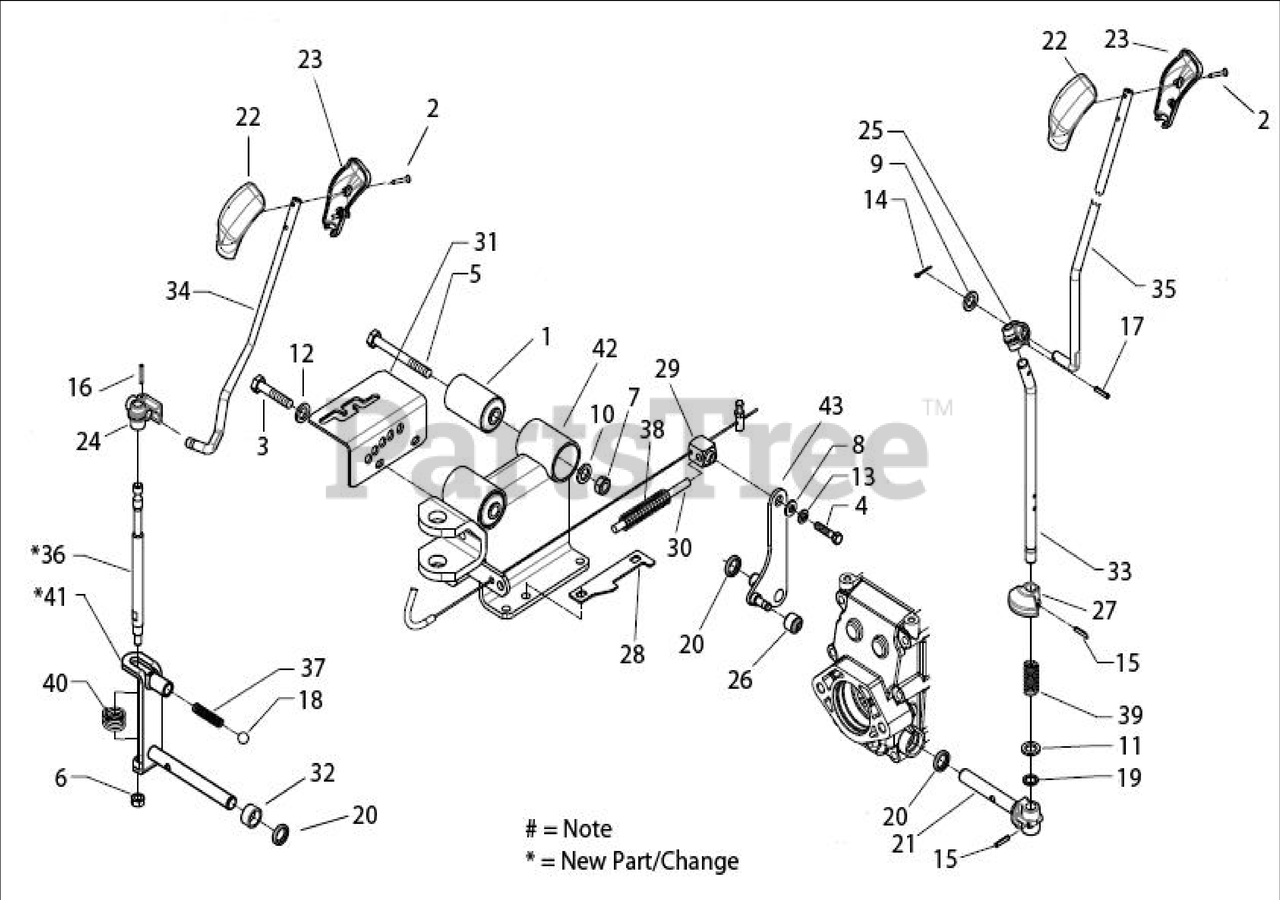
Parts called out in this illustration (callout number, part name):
1	SILENT BLOCK, 12X40X58X66
2	SCREW M5X25
3	CAPSCREW, M8X14
4	CAPSCREW, M8X12
5	CAPSCREW, M12X100
6	NUT, SELFLOCKING, M8
7	NUT, SELFLOCKING, M12
8	WASHER FLAT M8.4
9	WASHER FLAT M10.4
10	WASHER FLAT, M13X25
11	WASHER FLAT M13
12	WASHER, SUPER M8
13	WASHER, LOCK M8.4
14	COTTER PIN M2X15
15	PIN SPIROL M4X20
16	PIN SPIROL M3X22
17	PIN SPIROL M4X24
18	BALL 15/32
19	O-RING
20	OIL SEAL M14X22X4
21	SHAFT, PTO
22	HANDLE LOWER (BLACK)
23	HANDLE UPPER (BLACK)
24	JOINT
25	ARTICULATION, PTO
26	PTO LOCKOUT ROLLER
27	PTO LOCK OUT
28	LEVER, REVERSE SPEED
29	BLOCK, REVERSER
30	PIN, GUIDE
31	GEAR QUADRANT
32	SPACER
33	SHIFT ARM, PTO
34	CONTROL ROD, SPEED
35	CONTROL ROD, PTO
36	LEVER, ARM SPEED
37	SPRING, QUADRANT DETENT
38	SPRING, REVERSER
39	SPRING, PTO SHIFT ARM
40	SPRING, LEVER ARM SPEED
41	LEVER, SPEED SELECTOR
42	SUPPORT, STEERING COLUMN
43	LEVER, REVERSER, PTO LOCK OUT
